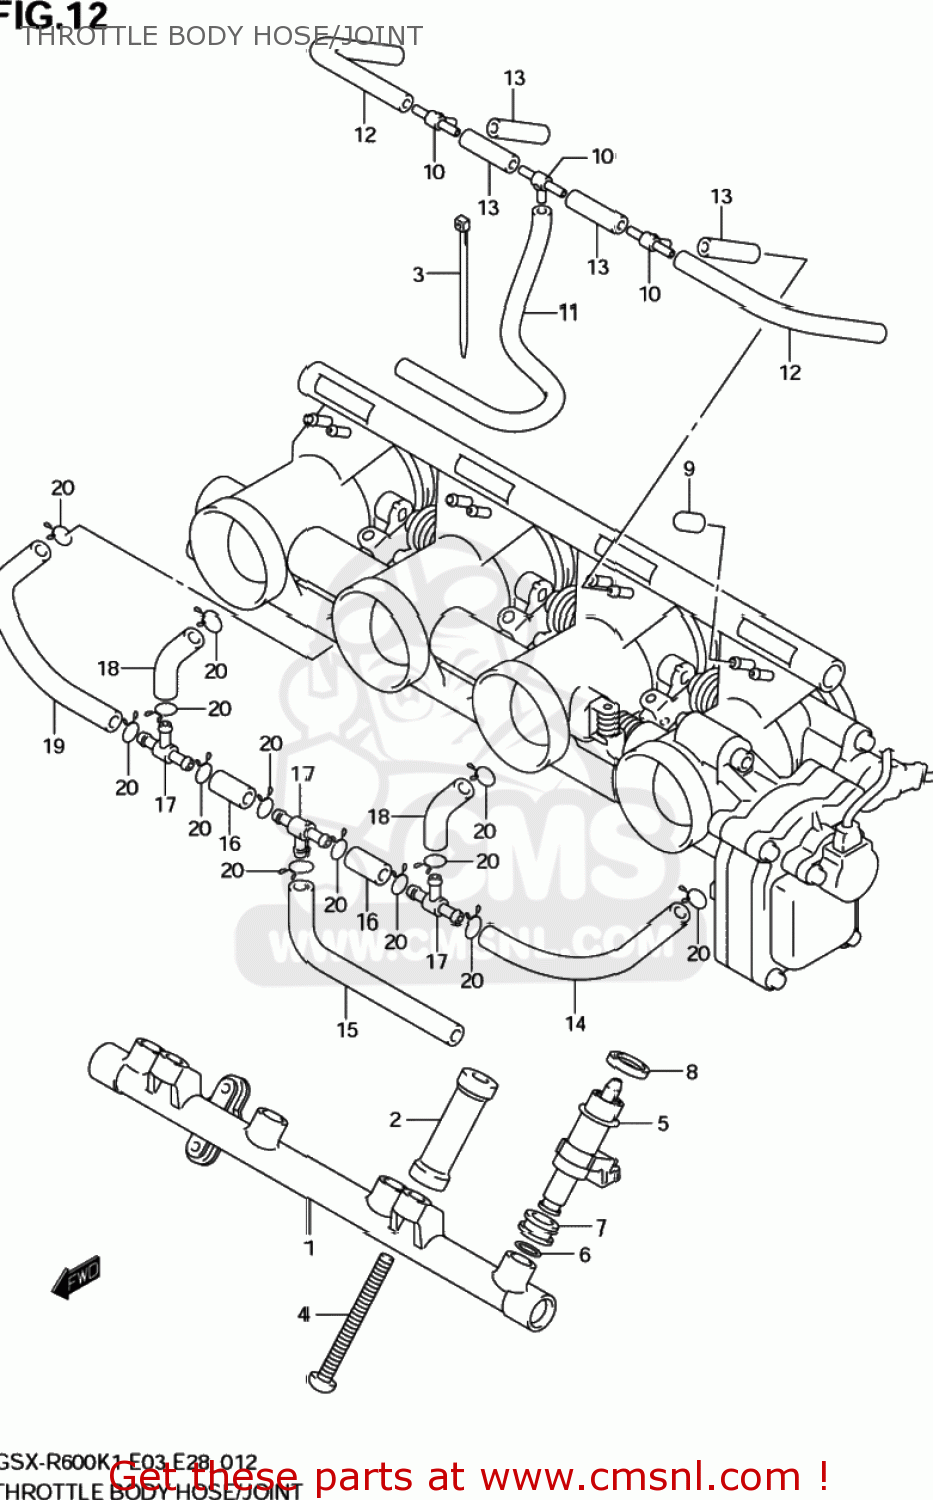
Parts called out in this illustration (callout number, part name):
1	DELIVERY PIPE ASSY
2	PIPE
3	CLAMP
4	SCREW
5	INJECTOR ASSY
6	O RING
7	RING,CUSHION
8	RING,SEAL
9	CAP
10	3WAY,VACUUM HOSE
11	HOSE(3.2X7.4X225)
12	HOSE(3.2X7.4X225)
13	HOSE(3.2X7.4X225)
14	HOSE ASSY
15	HOSE ASSY
16	HOSE
17	NIPPLE
18	HOSE
19	HOSE ASSY
20	CLIP
